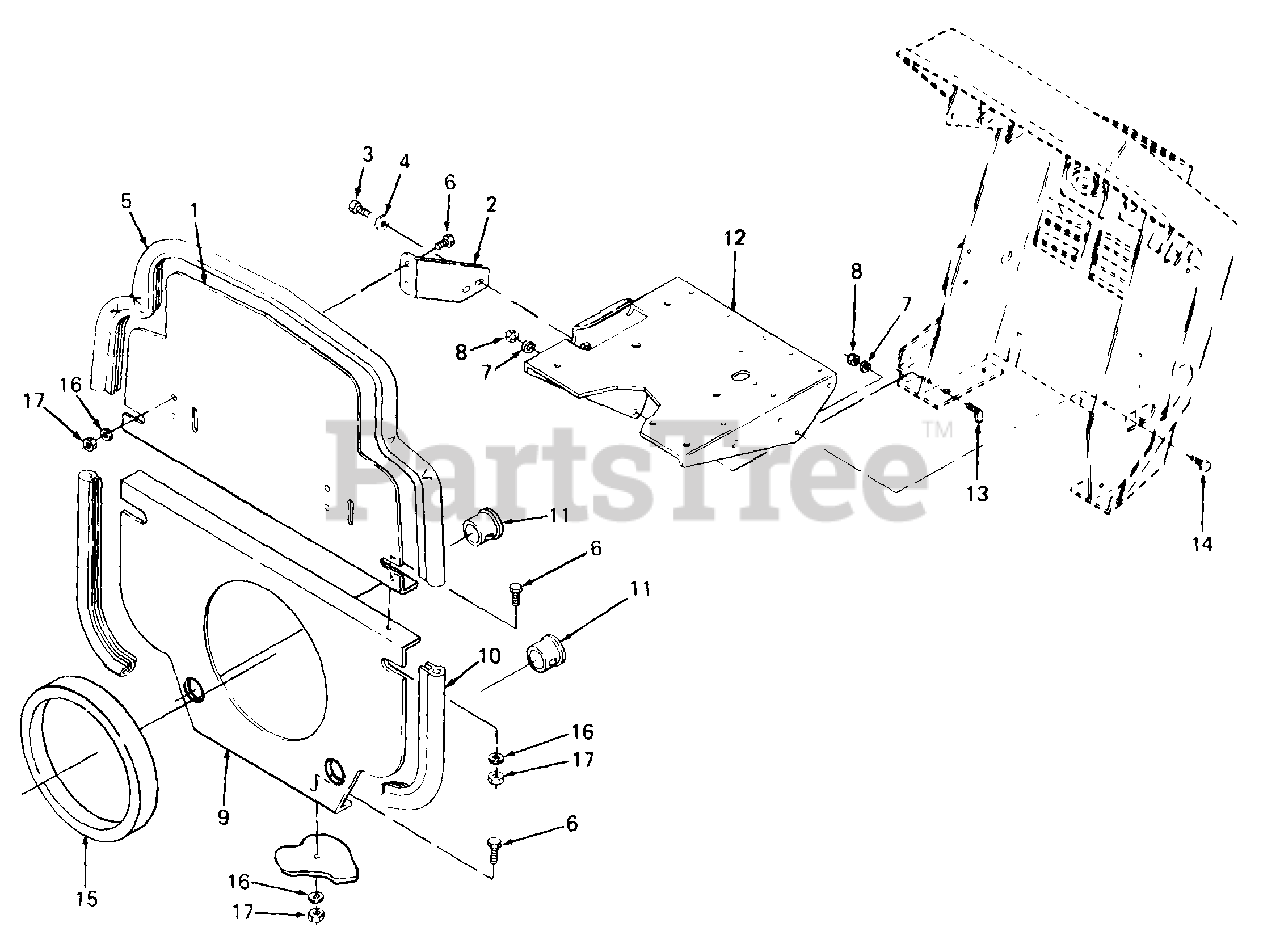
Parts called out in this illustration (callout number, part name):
3	Screw, Hex Cap, 5/16-18 x .50 Lg GR5
4	Washer, Bell, .345 x .88 x .060 Thk
5	Seal, Bulkhead, 36" Lg
6	Screw, Hex Cap, 1/4-20 x .50 Lg GR5.
7	Washer, Lock, 1/4
8	Nut, Hex, 1/4-20 GR5
9	Bulkhead, Lower
10	Seal, Bulkhead, 10" Lg
11	Bushing, Snap, 7/8 ID
12	Tray Assy, Battery
13	Bolt, J-Type, 1/4-20
14	Screw, Hex Cap, 1/4-20 x 62 Lg GR5
15	Ring, Foam Sealing
16	Washer, Bell, .265 x 75 x .062 Thk
17	Nut, Hex Top Lock, 1/4-20
